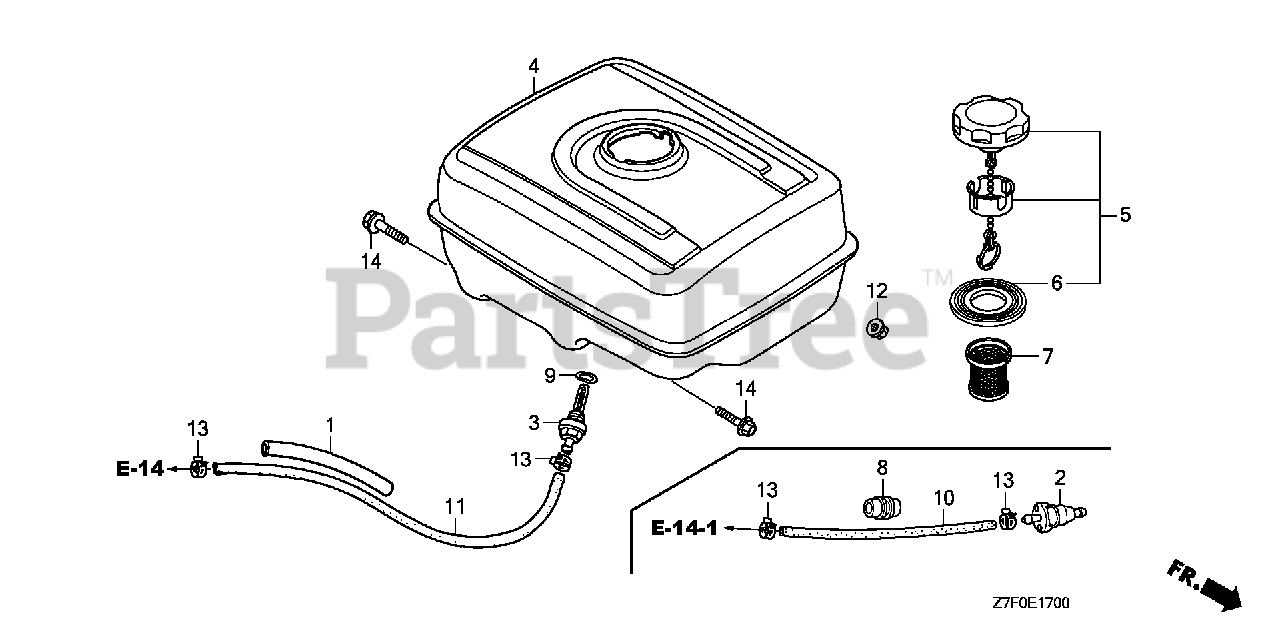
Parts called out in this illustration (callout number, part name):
1	RUBBER, SUPPORTER (107MM)
3	JOINT, FUEL TANK
4	TANK, FUEL *NH1* (BLACK)
4	TANK, FUEL *NH31* (MCKINLEY WHITE)
5	CAP, FUEL FILLER (CHROME PLATED)
5	CAP, FUEL FILLER
6	GASKET, FUEL FILLER CAP (39X62X3) (RADICON)
6	GASKET, FUEL FILLER CAP (39X62X3)
7	FILTER, FUEL
9	O-RING (13.5X1.5) (ARAI)
9	O-RING (14MM) (NOK)
11	TUBE, FUEL (4.5X235) (FKM)
12	NUT, FLANGE (8MM)
13	CLAMP, TUBE (D8)
14	BOLT, FLANGE (8X25)
